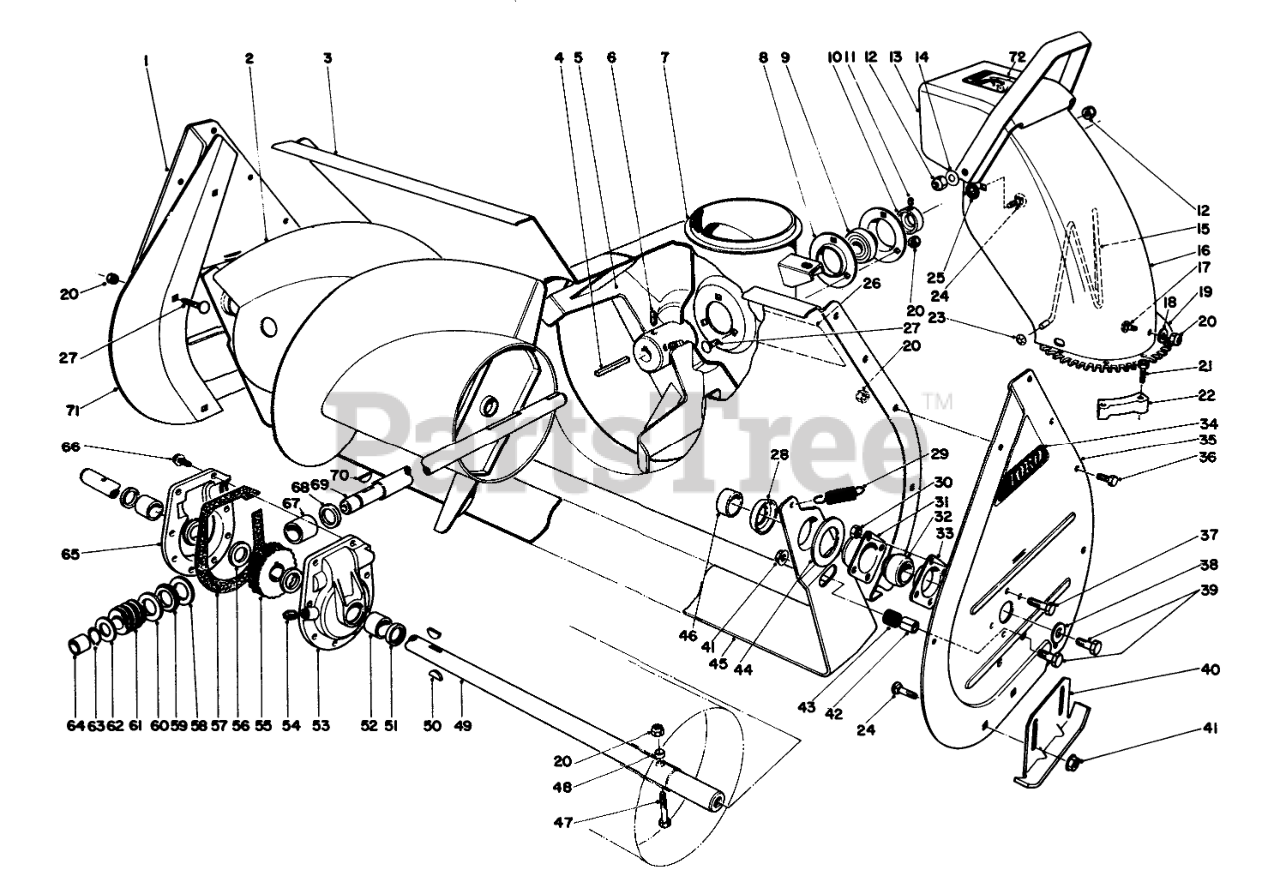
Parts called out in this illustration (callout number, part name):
1	RH AUGER SIDE PLT R
2	RH AUGER ASM - 32"
3	Auger Housing
5	IMPELLER ASM
6	Set Screw
7	CHUTE RING
8	BRG FLANGE
9	Bearing-lmpeller (Incl. Ref. 10 & 11)
10	EXT LOCKING COLLAR
11	SCREW-HSH
12	NUT-LOCK, CONE
13	Deflector
14	WASHER-BELLEVILLE
15	WIRE-CHUTE
16	Upper Chute
17	SCREW-CARR
18	WASHER-PLAIN
19	Screw
20	NUT-LOCK, NI
21	SCREW-SPECIAL
22	RETAINER-CHUTE
23	NUT-PUSH
24	SCREW-CARR
25	Rubber Washer
26	Decal-Warning
27	BOLT-CARR
28	Positioner-Scraper
29	SPRING-TENSION
30	NUT-LOCK, CONE
31	BEARING-FLANGE, FRONT
32	BEARING
33	BEARING-FLANGE, REAR
34	AUGER SIDE PLT DECAL
35	LH AUGER SIDE PLT R
36	SCREW-HH
37	SCREW-HH
38	WASHER
39	SCREW-HH
40	AUGER SKID WA R
41	NUT-HF
42	SCRAPER STOP SPACER
43	SCRAPER STOP CUSHION
44	SCRAPER BLADE SPACER
45	SCRAPER BLADE 32" R
46	AUGER SPACER
47	Auger Bolt
48	SPACER-HUB, AUGER
49	32 AUGER SHAFT
50	KEY-WOODRUFF
51	SEAL-OIL
52	BUSHING
53	Gear Case Bushing Assy.-L.H.(Incl. Ref. #51, 52)
54	PLUG-PIPE, SQH
55	GEAR-WORM, 27T
56	WASHER-THRUST
57	GASKET-CASE, GEAR
58	WASHER-THRUST
59	BEARING-THRUST
60	THRUST-WASHER
62	WASHER-THRUST
63	Ring-Snap
64	BUSHING
65	Gear Case Bushing Assy.-R.H. (Incl. Ref. #51, 52)
66	SCREW-TAPTITE
67	BUSHING-SPECIAL
68	RING-QUAD
69	SHAFT-IMPELLER
70	KEY-WOODRUFF
71	Auger Housing Extension R.H.
72	Decal-Danger
